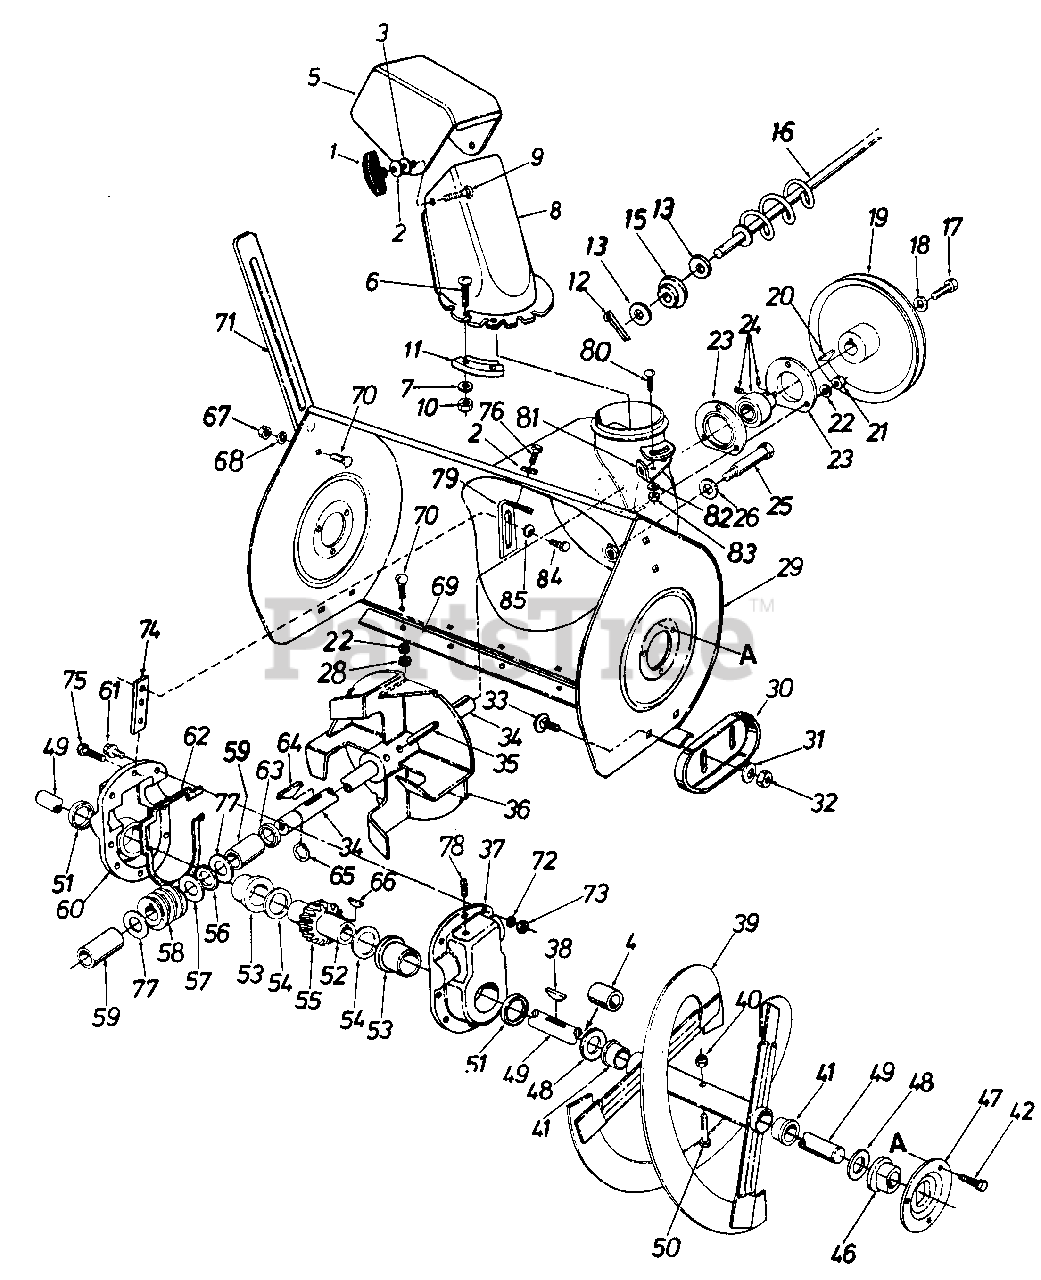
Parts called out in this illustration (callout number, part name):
1	KNOB-HANDLE ASSY
2	WASHER-BELL .337 X .867 X .057
3	WASHER-FL-.312 X 1.125 X .125
5	CHUTE-UPPER
6	SCREW-TRUSS MACH
7	WASHER-FL-.281 ID X .50 OD X .063
8	CHUTE-LOWER
9	BOLT-CARRIAGE 5/16-18 X 1.00
10	NUT-HEX CENTER L-1/4-20
11	KEEPER-CHUTE FLANGE
12	PIN-COTTER-3/32 DIA X .75
13	WASHER-FL-.385 ID X .62 OD X .063
15	BEARING
16	CRANK ASSY-CHUTE
17	SCREW-HEX 5/16-18 X .88 SPECIAL
18	WASHER-BELL .337 X .867 X .057
19	PULLEY-V-1/2 ID X 10.0 OD
20	KEY-HI-PRO #9-3/16X3/4 DIA-HDN
21	BOLT-CARRIAGE 5/16-18 X 1.25
22	WASHER-LOCK-5/16
23	HOUSING-BRG
24	BEARING-SELF ALIGN
25	STUD-3/8-16X2.75
26	WASHER-BELL .400 ID X .88 X .060
28	NUT-HEX 5/16-18
29	HOUSING ASSY-BLOWER
30	SLIDE SHOE
31	WASHER-BELL .400 ID X .88 X .060
32	NUT-HEX JAM 3/8-18
33	BOLT-CARRIAGE 3/8-16 X .62
34	AXLE-BLOWER
35	PIN-SPRING SPIR 5/16 X 1.75
38	KEY-WOODRUFF #91-1/4X3/4 DIA-HDN
42	SCREW-HEX HD TAP
46	BEARING-FLANGE
47	HOUSING-BRG
48	WASHER-FL
49	AXLE-SPRIAL
50	BOLT-HEX 5/16-18X1.75
51	SEAL-OIL
52	SHAFT-WORM GEAR
53	BEARING-FLANGE
54	WASHER-FL-1.50 X 2.25 X .030
55	GEAR-WORM-LH-DBL THD
56	BEARING-THRUST
57	WASHER-FL-881.D.X1.40 O.D.X.155
58	GEAR-WORM-LH-DBL THD
59	SLEEVE
60	HOUSING W/FL BRG-RH-GEAR
61	SCREW-HEX 5/16-18 X 1.00
62	GASKET-RUBBER
63	SEAL-OIL
64	KEY-HI-PRO #9-3/16X3/4 DIA-HDN
65	RING-SNAP FOR .875 SHAFT
66	KEY-WOODRUFF #91-1/4X3/4 DIA-HDN
67	NUT-HEX 5/16-18
68	WASHER-LOCK-5/16
70	BOLT-CARRIAGE 5/16-18 X .62
71	CUTTER-DRIFT
72	WASHER-SHAKE PROOF
73	NUT-HEX INS L-5/16-18
74	PLATE-SUPPORT-GEAR HSG
75	SCREW-HEX 5/16-18 X 1.25
76	SCREW-HEX HD TAP
77	WASHER-FL-881.D.X1.40 O.D.X.155
78	PLUG-VENTED-PLASTIC
80	BOLT-CARRIAGE 5/16-18 X .75
82	WASHER-BELL .337 X .867 X .057
83	NUT-HEX 5/16-18
84	SCREW-HEX 1/4-28 X .75
85	WASHER-SPRING BELL
